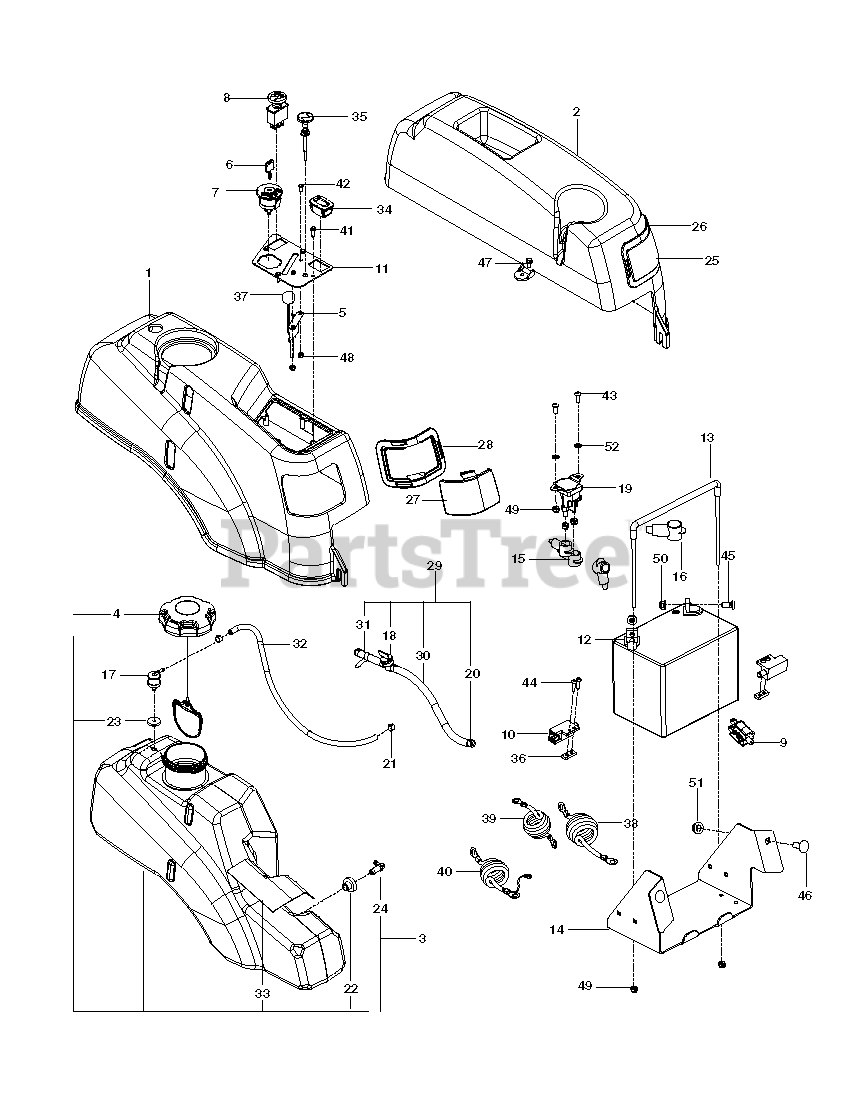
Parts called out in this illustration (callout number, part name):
1	FENDER RT, BLACK
2	FENDER, LT, BLK
3	FUEL TANK ASM, LARGE
4	CAP, FUEL
5	THROTTLE CABLE
7	IGNITION SWITCH
9	SWITCH, BRAKE 3P
13	BATTERY TIE DOWN ASSEMBLY
14	BOX, BATTERY, BLACK
15	TERMINAL COVER-SM
16	INSULATOR
17	VALVE.FUEL.CHECK
18	FUEL VALVE
19	SOLENOID
20	HOSE CLAMP
21	CLAMP, HOSE
22	RUBBER GROMMET
23	GROMMET, CHECK VALVE
25	PANEL, LT
26	RING, LT BLK
27	PANEL, RT, BLK
28	RING, TRIM, RT-BLK
30	GAS LINE 10"
31	FUEL LINE 14"
32	HOSE, VAPOR 3/16 X 48"
35	CHOKE CABLE
36	TAPPED PLATE
37	KNOB ROUND BALL
38	CABLE POSITIVE, LONG
39	BATTERY CABLE, NEGATIVE
41	SCR #10-12X3/4 HEX WAS HD ZD
42	HCS #10-24 X 1/2
43	SCR 1/4-20 X 5/8 BTN SKT HD ZD
44	SCR #10-24 X .75 SKT HD BLK
45	BOLT 5/16C X 3/4" CARRIAGE
46	RHSNB 3/8C X 1
47	BOLT 1/4-20 X 1/2 HWST
48	NUT 10-24 NYLOC
49	NUT 1/4-20 NYLOC
50	5/16-18 NYLOC FLANGE NUT
51	NUT 3/8-16 HEX FLG NYLOC ZD
52	WASHER 1/4 INT TOOTH
